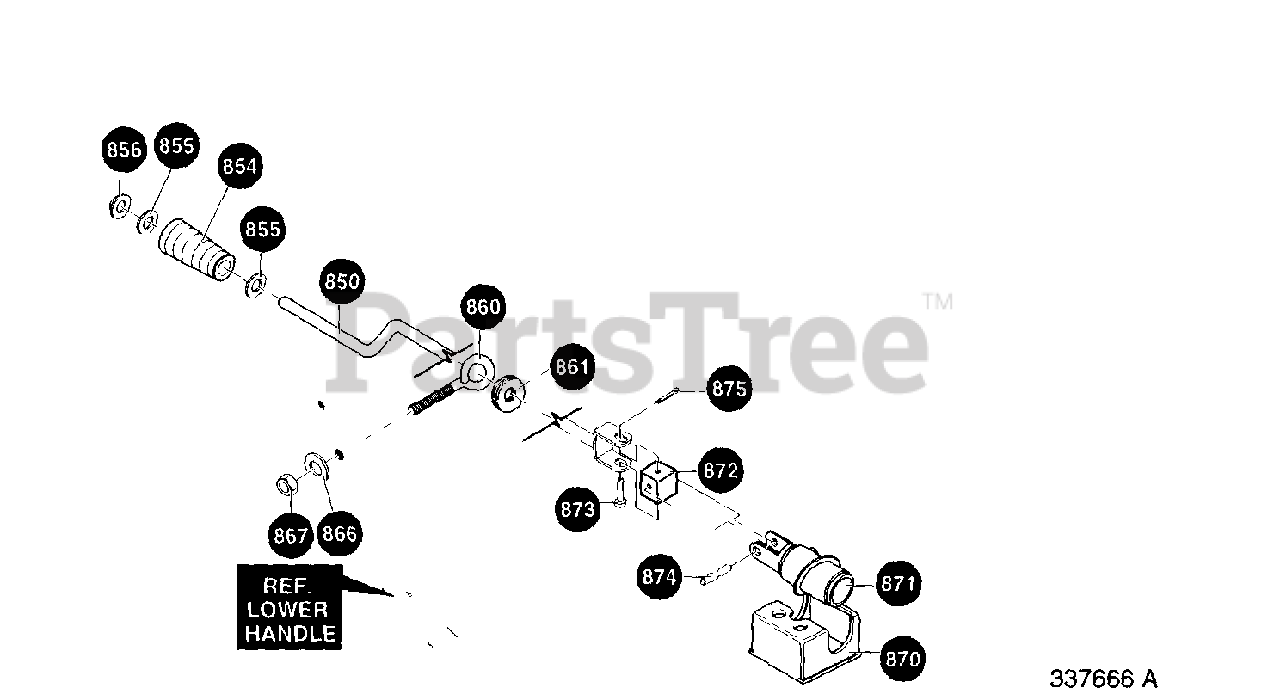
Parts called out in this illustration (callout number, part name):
850	Crank, Assy w/Yoke
854	Handle, Chute Crank
855	Flatwasher, .39 x.70 x.05
856	Ring, Ret E
861	Grommet, Eye Bolt
866	Flatwasher, .406 x .81 x .065
867	Nut, 3/8-16
870	Bracket, Worm
871	Worm, Gear Chute
872	Block, Univ Piv
873	Pin, Clevis
874	Pin, Univ Joint
875	Pin, Cotter
